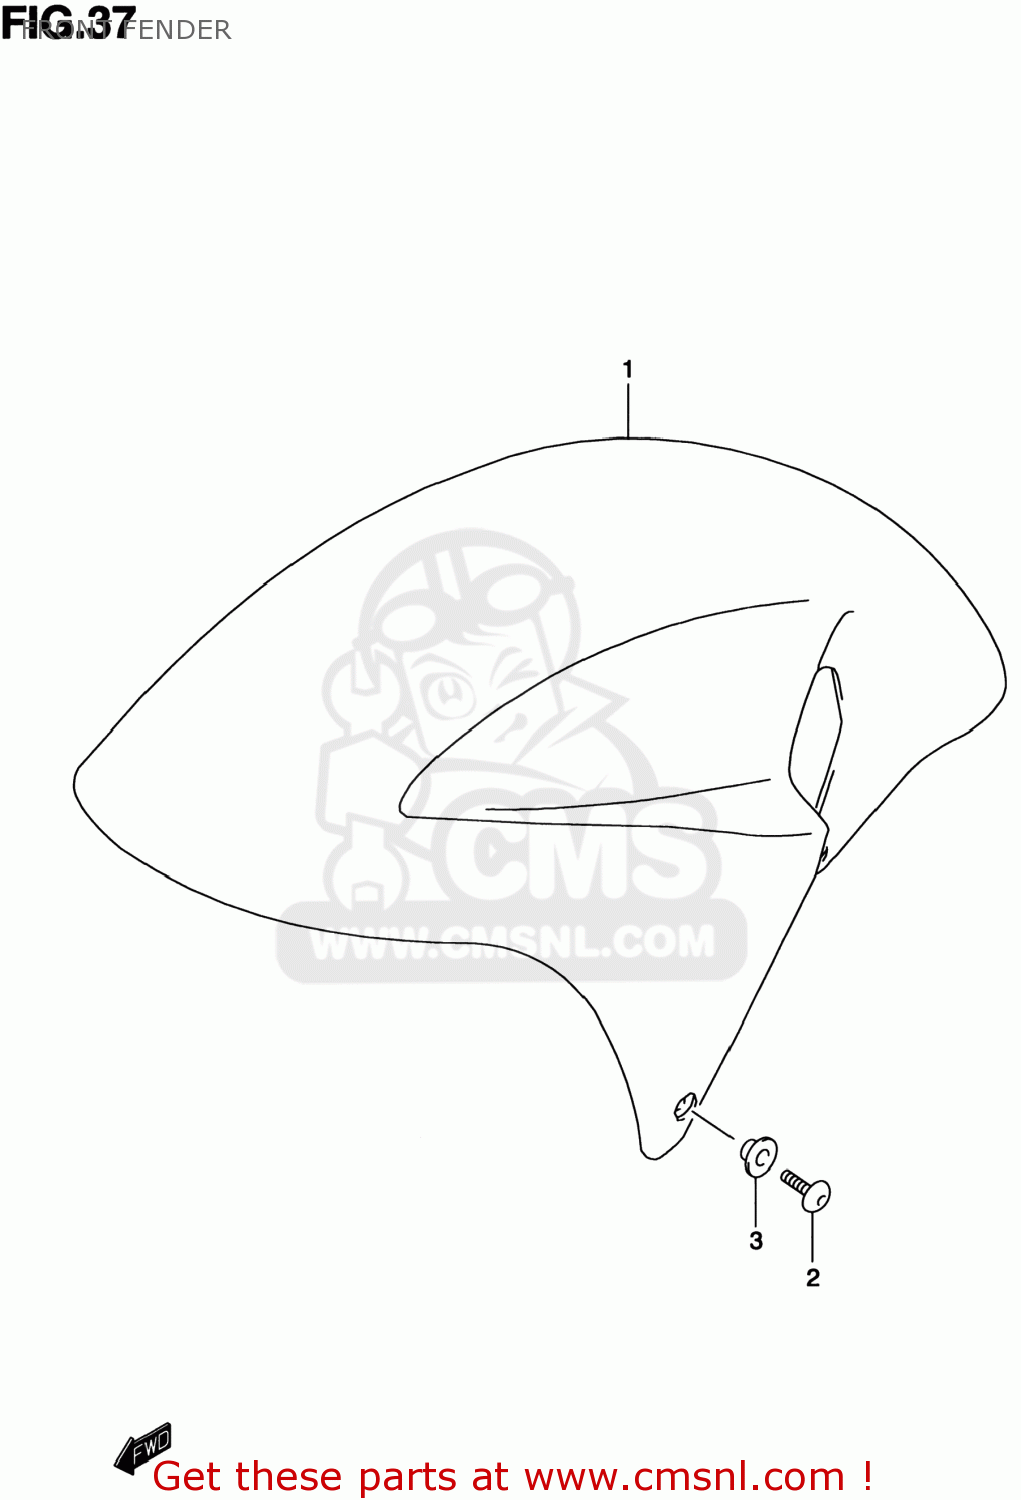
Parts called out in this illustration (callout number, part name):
1	FENDER COMP,FRONT
2	SCREW(6X16)
3	WASHER(6.3X16X1.5)
